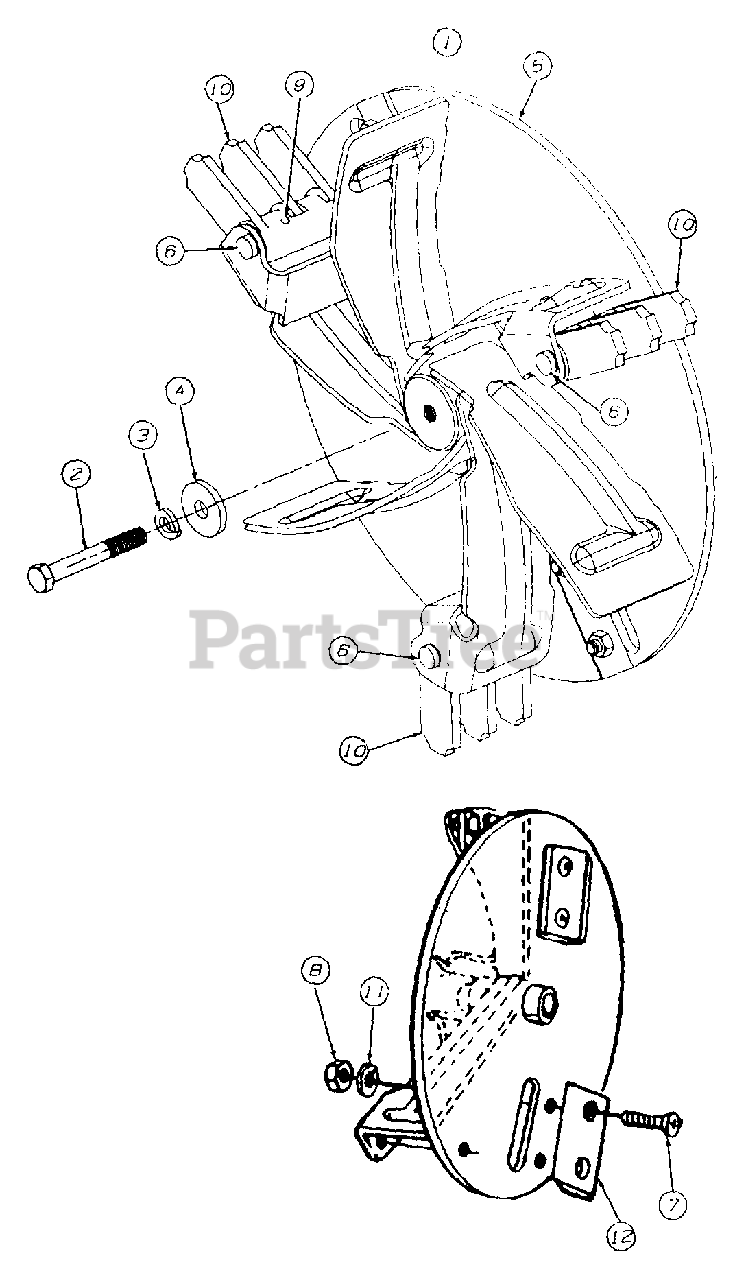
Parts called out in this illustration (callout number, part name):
1	IMPELLER ASSY COMP.
2	SCREW-HEX
3	WASHER-LOCK
4	WASHER-FLAT
5	IMPELLER ASSY
6	P IN-CLEVIS
7	SCREW-FLAT HEAD
8	NUT-HEX LOCK
9	PIN-ROLL SPRING
10	BLADE-FLAIL
11	WASHER-LOCK
12	BLADE-CHIPPER
